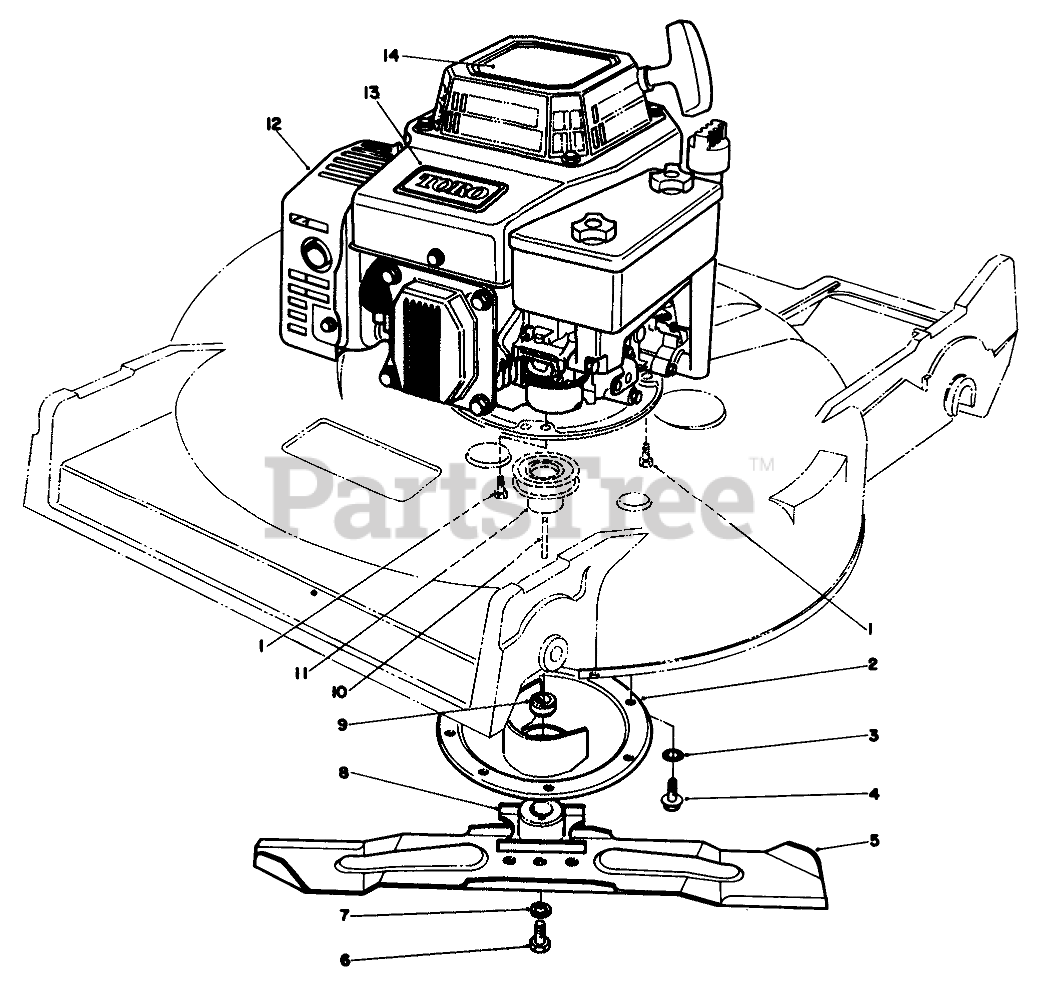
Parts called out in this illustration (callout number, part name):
1	SCREW-HWHTF
2	Crankshaft Protector Assy.
3	WASHER-LOCK, INTERNAL
4	SCREW-HWHTF
5	BLADE-21in
6	SCREW-BLADE
7	WASHER-LOCK
8	RETAINER-BLADE
9	SPACER-BLADE RETAINER
10	KEY-SQUARE
11	PULLEY-DRIVER
13	Plate-Logo
14	LOGO PLATE - RECOIL
